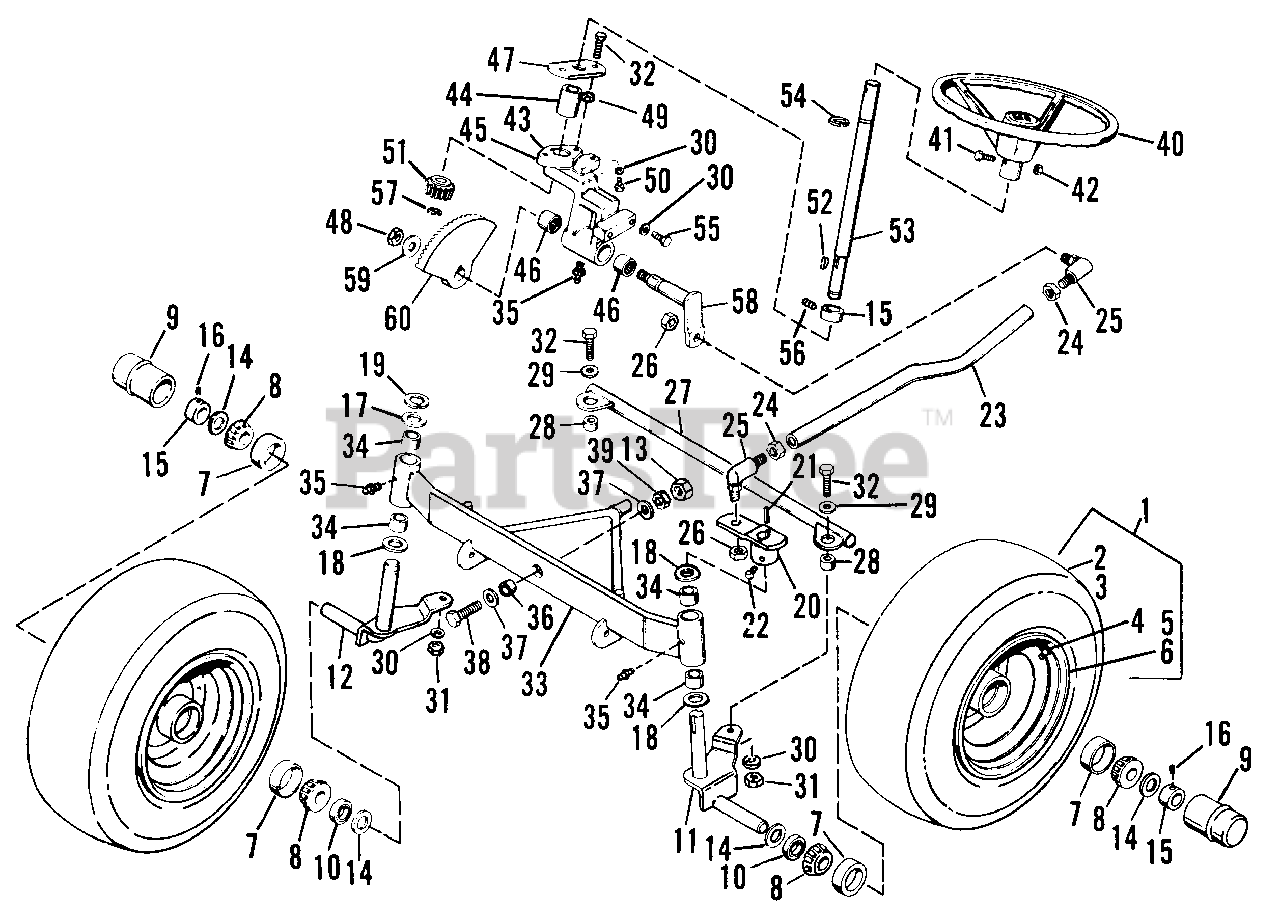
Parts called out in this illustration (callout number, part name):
1	Wheel & Tire Assembly
4	Valve Stem & Cap
5	Wheel-Sub Assembly
6	Wheel (Front)
7	Bearing, Cup
8	Bearing, Cone (Without Seal)
9	Hub Cap
11	Spindle Assy., L.H.
12	Spindle Assy., R.H.
13	Hex Jam Nut, 1/2"-13
15	Collar, Set
16	Set Screw, 5/16"-18 x 5/16"
17	Washer (Use Beneath Snap Ring)
19	Ring, Retaining
20	Arm Assy., Strg. L.H.
22	Set Screw, 5/16"-18 x 1/2"
24	Hex Jam Nut, 1/2"-20 N.F.
25	Joint, Ball
26	Hex Nut, Jam Lock, 1/2"-20
27	Link Assy., Drag
29	Washer, Plain, 3/8"
30	Lockwasher, 3/8"
31	Full Hex Nut, 3/8"-16 N.C.
32	Hex Capscrew, 3/8"-16 x 1-1/4"
33	Axle Assy., Front
35	Fitting, Grease
37	Plain Washer, 1/2"
38	Hex Capscrew
39	Nut, Toplo, 1/2"-13
40	Steering Wheel
41	Hex Capscrew, 5/16"-18 x 1-1/4"
42	Nut, Flange, Lock 5/16-18
43	Steering Bracket, Casting
44	Bushing, Steering
45	Casting and Bearing
46	Bearing, Needle
47	Plate, Steering
48	Hex Lock Nut, 7/16"-14 N.C.
49	Hex Jam Nut, 3/8"-16
50	Hex Capscrew, 3/8"-16 x 3/4"
51	Pinion, 15T, Bevel
52	Key, Woodruff
53	Shaft, Steering
54	Ring, Retaining
55	Hex Capscrew, 3/8"-16 x 7/8"
56	Set Screw, 5/16"-18 N.C. x 1/4"
57	"E" Ring
58	Arm Assy. Steering
59	Plain Washer, 7/16"
60	Gear, 23T, Bevel
